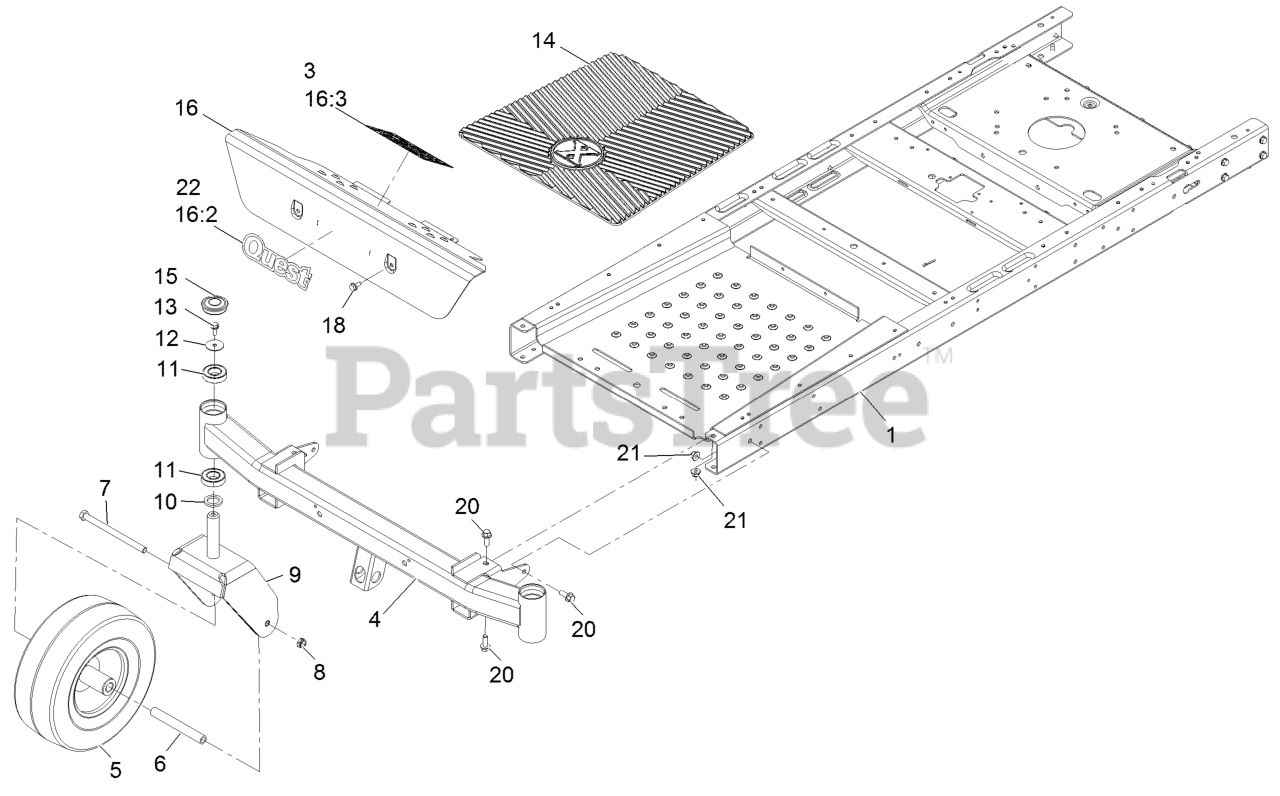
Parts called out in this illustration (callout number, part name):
1	FRAME ASM
3	DECAL-DANGER
5	13 INCH WHEEL AND TIRE AS
6	SPANNER
7	WASHER-LOCK
8	NUT-HEX
9	FORK-CASTER
10	WASHER-THRUST
11	BEARING-BALL
12	WASHER-FLAT
13	SCREW-HHF
14	MAT-FLOOR
15	CAP-GREASE
16	FOOTREST ASM
16:3	DECAL-DANGER
18	Screw-HWH 5/16-18 X 3/4 Tf
20	SCREW-HHF 3/8-16 X 1
21	NUT-HF, NI
